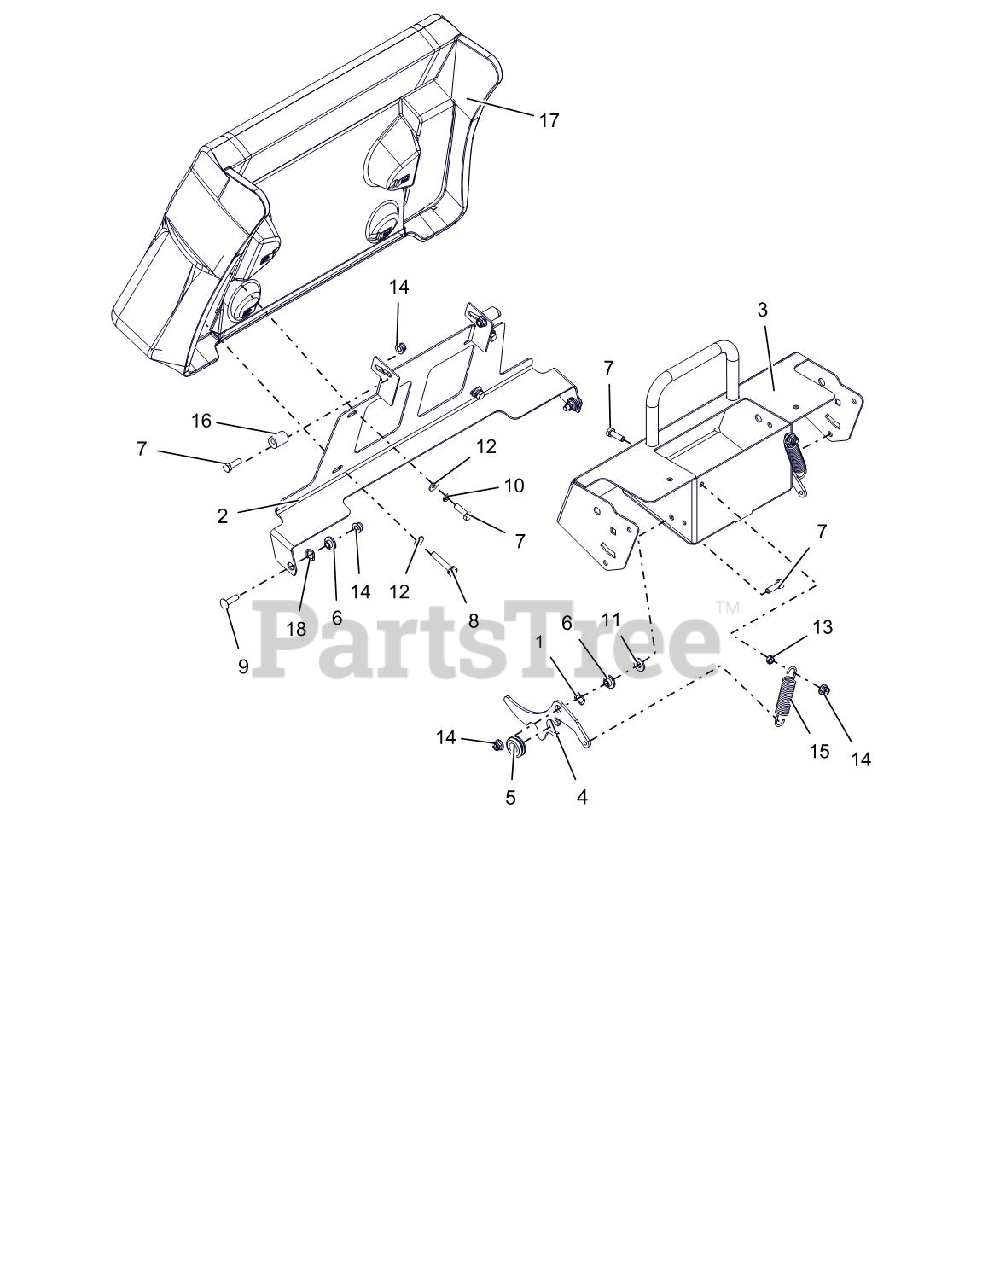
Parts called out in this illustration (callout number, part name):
1	WAVE WASHER .531X.781X.125FH
2	PAD, MOUNT
3	WLDMT, CONTROL PANEL PROSTANCE
4	LATCH, PAD MOUNT
5	GROMMET, SPLIT RUBBER
6	BSHG-FLG .32X.500X.344X.880
7	@BLT-HEX .31-18X1.00 GR5 YWZC
8	@BLT-HEX .31-18X1.75 GR5 YWZC
9	BLT-RDHDSQSHNK.31-18X1.13 G5YZ
10	@WSHR-LK .31X.078 REG YWZC
11	@WSHR-FL-STL.38X.875X.083 YWZC
12	@WSHR-FL-STL.312X.734X.065 YWZ
13	@NUT-LK-CTR-JAM .31-18 YWZC
14	@NUT-LK-NYL-FLG .31-18 YWZC
15	SG-TENS .105X.812X3.88 WLD 15
16	ECCENTRIC
17	PAD, PRO-STANCE OPERATOR
18	WAVE WASHER .531X.781X.125FH
